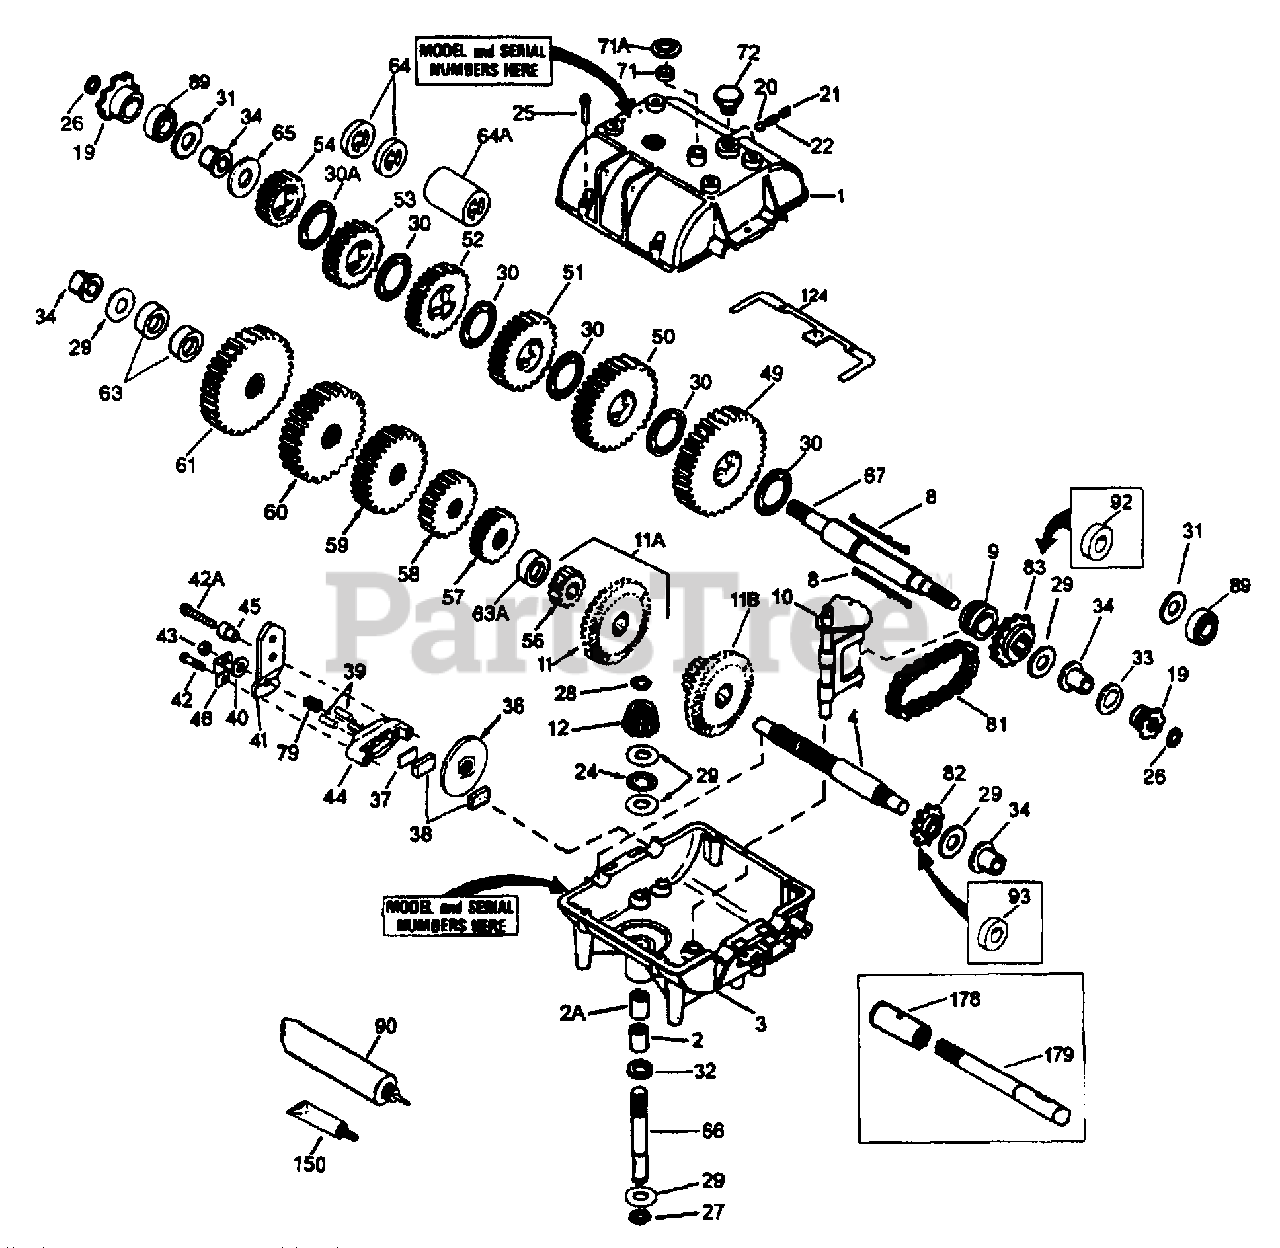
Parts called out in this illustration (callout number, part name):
1	Case, Transmisson
2	Needle Bearing Grease Spec
2A	Needle Bearing
3	Case, Transmission
8	Shift Key
9	Shift Collar
10	Shift Rod & Fork
11	Bevel Gear (42 teeth)
12	Bevel Pinion (14 teeth-steel)
20	Steel Ball, 5/16" dia.
21	Set Screw, 3/8-16 x 3/8"
22	Spring
24	Thrust Bearing
25	Screw, 1/4-20 x 1-1/4" (6)
27	Retaining Ring
28	Retaining Ring
29	Washer (6)
30	Washer (5)
32	"O" Ring
34	Flanged Bushing
49	Spur Gear (37 teeth)
50	Spur Rear (35 teeth)
51	Spur Gear (32 teeth-steel)
52	Spur Gear (30 teeth)
53	Spur Gear (25 teeth)
56	Spur Gear (12 teeth-steel)
57	Spur Gear (15 teeth)
58	Spur Gear (18 teeth-steel)
59	Spur Gear (20 teeth)
60	Spur Gear (25 teeth)
65	Washer
66	Input Shaft (3-11/16" long)
67	Shifter & Brake Shaft
71	Square Cut Ring
72	Threaded Plug
81	Roller Chain (No. 41 chain, 24 links)
82	Sprocket (9 teeth)
83	Sprocket (18 teeth)
90	Grease (32 oz. bottle Bentonite grease)
150	Gasket Eliminator (Loctite #515)
178	Coupling
179	Connector Shaft
